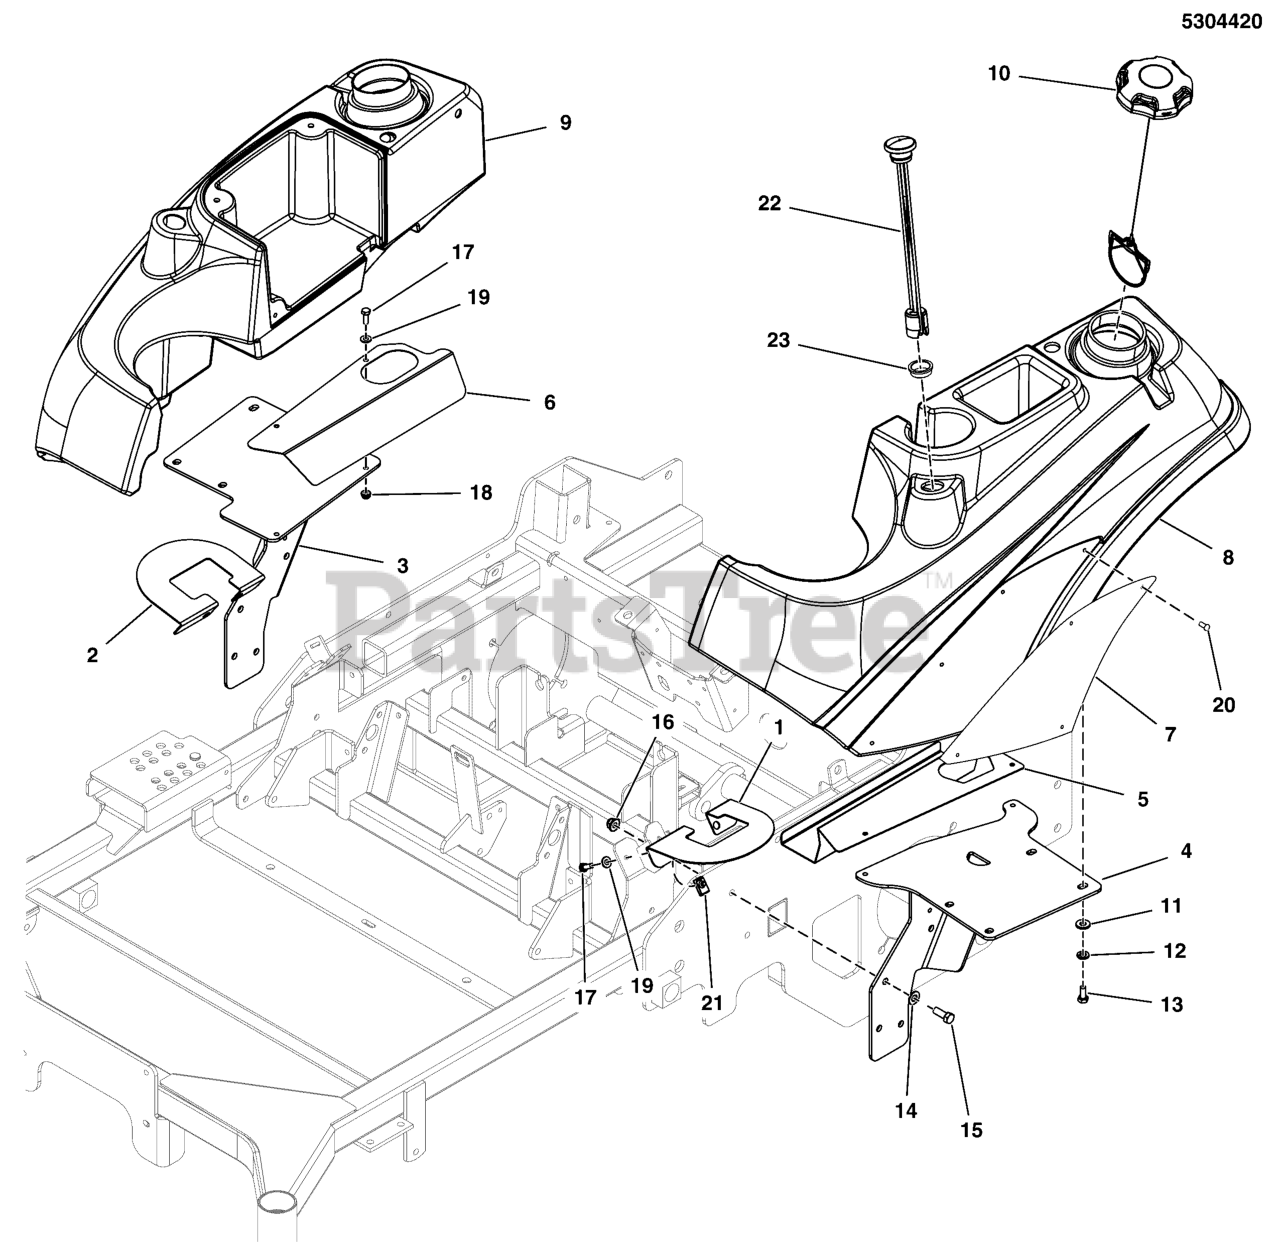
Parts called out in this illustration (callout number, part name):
1	PLATE,MOTION CONTROL GUARD,F320Z LH -BLK
2	PLATE,MOTION CONTROL GUARD,F320Z RH -BLK
3	WELD, FUEL MOUNT, RH - BLK
4	WELD, FUEL MOUNT, LH - BLK
5	GUARD, FUEL MOUNT, F320Z, LH - BLK
5	GUARD, FUEL MOUNT, LH - BLK
6	GUARD, FUEL MOUNT, F320Z. RH - BLK
6	GUARD, FUEL MOUNT, RH - BLK
7	BADGE, IS2000 - IS3000 - RED
8	TANK, FUEL, LH
9	TANK, FUEL, 5.25 GAL,MED, Z-RH, LOW PERM
10	FUEL CAP, 3-1/2", MANAGED VENT OUT, 12"
11	WASHER, 5/16 F436 FLAT
12	WASHER, 5/16 LOCK CZ
13	BOLT, 5/16-18 X 3/4 GD5
14	WASHER, 3/8 SAE
15	BOLT, 3/8-16 X 1" GD5 CZ
16	NUT, 3/8-16 HEX NYLOCK FLANGE
17	BOLT, 1/4-20 X 3/4 GD5 CZ
18	NUT, 1/4-20 HEX NYLOCK FLANGE
19	WASHER, 1/4 SAE
20	SCREW, #10-24 X 3/8 ALLEN BHBZ
21	BODY CLIP, 1/4-20 X 1/2 DEEP
22	GAUGE, FUEL, 12
23	GROMMET, FUEL GAUGE
